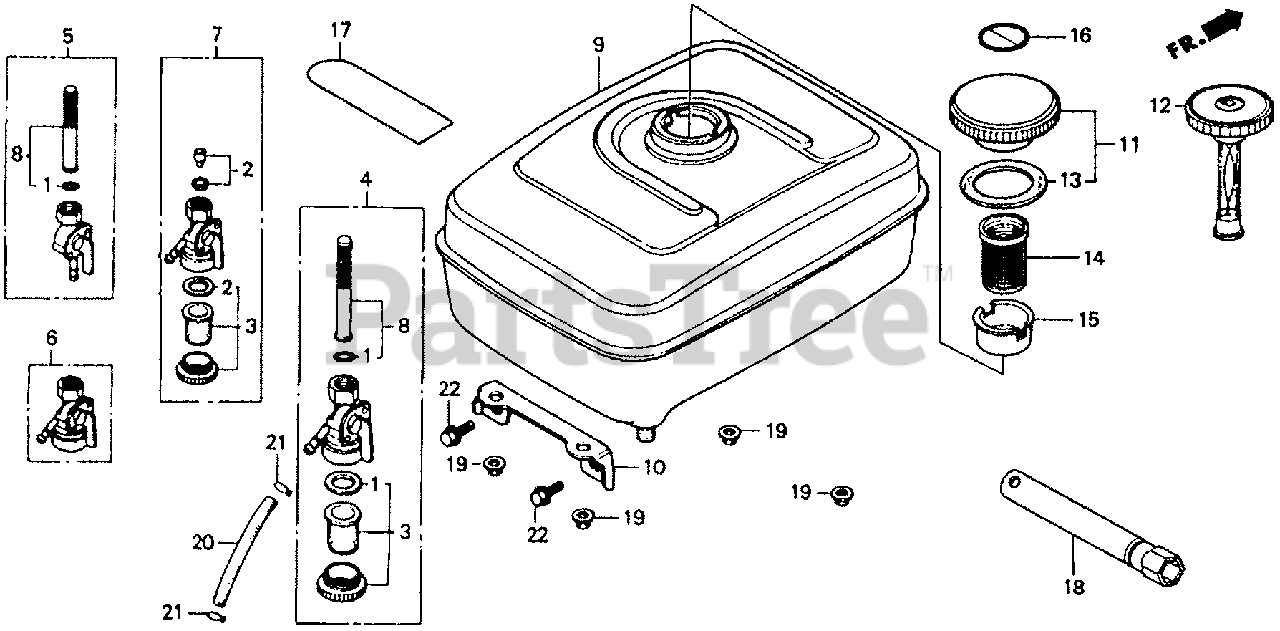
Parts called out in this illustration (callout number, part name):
1	GASKET SET, VALVE
2	GASKET SET, VALVE (NOT AVAILABLE)
3	CUP SET, FUEL STRAINER
4	PETCOCK ASSY.
5	PETCOCK ASSY.
6	PETCOCK ASSY.
7	PETCOCK ASSY.
8	SCREEN SET
9	TANK, FUEL *NH31* (MCKINLEY WHITE)
9	TANK, FUEL *NH31* (MCKINLEY WHITE) (NOT AVAILABLE)
10	STAY, FUEL TANK
11	CAP, FUEL FILLER
12	GAUGE, FUEL (ENGLISH)
13	GASKET, FUEL FILLER CAP
14	FILTER, FUEL
15	HOLDER, FUEL FILTER
16	MARK, CAUTION (EXTERNAL)
17	MARK, CAUTION (ENGLISH/FRENCH)(SPANISH)
18	WRENCH, SPARK PLUG
19	NUT, FLANGE (8MM)
20	BULK HOSE, FUEL (4.5X3000) (4.5X85)
21	CLIP, TUBE (B8)
22	BOLT, FLANGE (8X16)
